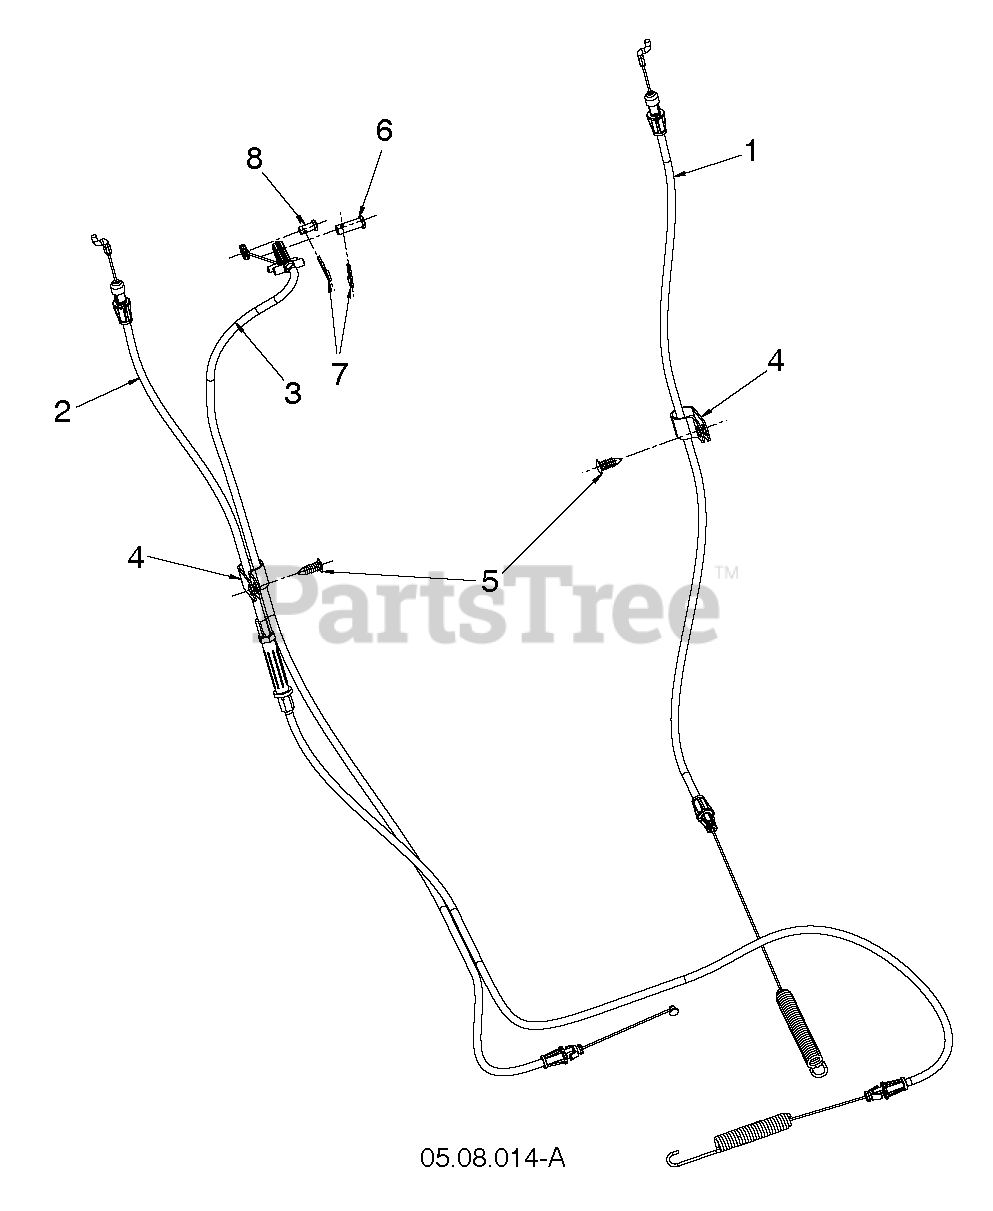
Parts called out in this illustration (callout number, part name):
1	CABLE.CONTROL.DRIVE.16
2	CABLE.CONTROL.AUGER
3	CABLE.CONTROL.SPEED.DSST.OPP
4	CLIP.CABLE.BLK
5	FASTENER.PUSH.O.250X0.783
6	PIN CLEVIS 5/16X.875
7	HAIRPIN.SOFT.ZINC.059X1.125
8	PIN CLEVIS .25 X .31
